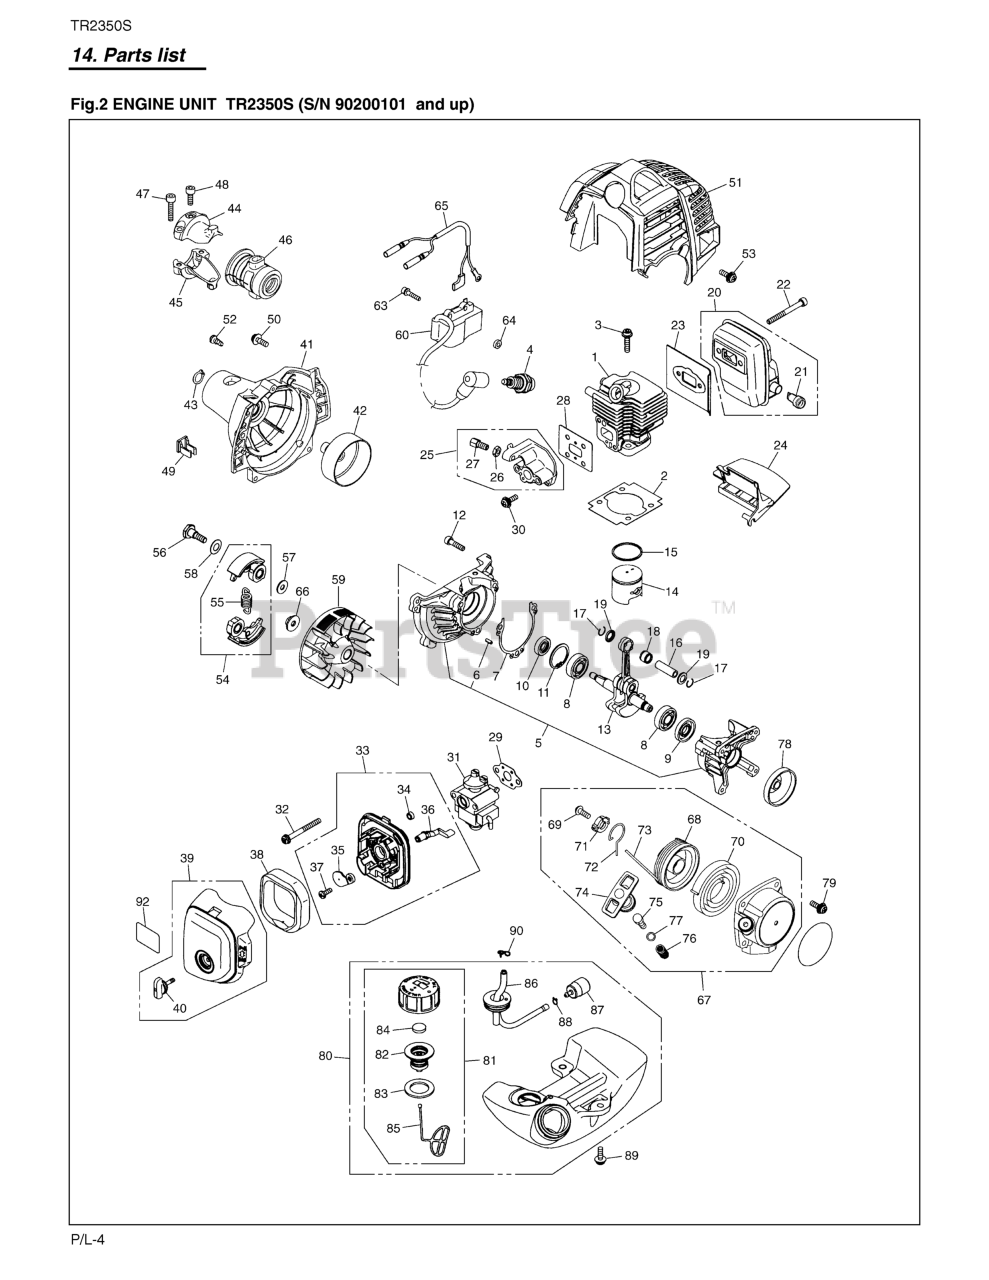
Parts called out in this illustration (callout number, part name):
1	CYLINDER
2	GASKET, BASE
3	BOLT, M5 X 22
4	PLUG (BPMR7A)(RPLS 5933-73110)
5	CRANKCASE-C
6	PIN
7	GASKET, CASE
8	BEARING
9	SEAL
10	SEAL
11	RING, SNAP M26x1.2 R-318013340
12	BOLT, M5 X 20
13	CRANKSHAFT-C
14	PISTON
15	RING, PISTON (RPLS 1850-41210)
16	PIN, PISTON 5x8x26
17	RING
18	BEARING
19	WASHER
20	MUFFLER-A
21	ARRESTER
22	BOLT, M5 x 50
23	GASKET
24	PLATE
25	INSULATOR-C
26	NUT
27	SCREW (RPLS 1918-81170)
28	GASKET (RPLS -13120)
29	GASKET (REPLACES -13130)
30	SCREW
31	CARBURETOR ASSY
32	SCREW (RPLS 0263-30550)
33	BODY ASSY.
34	SLEEVE
35	PLATE, CHOKE
36	LEVER
37	SCREW
38	ELEMENT
39	COVER-A
40	KNOB
41	HOUSING
42	DRUM
43	RING
44	BRACKET (A)
45	BRACKET (B)
46	CUSHION
49	CLAMP
50	SCREW
51	COVER, ENGINE
52	SCREW, M5 X 10
53	SCREW
54	SHOE COMP.
55	SPRING
56	BOLT
57	WASHER
58	WASHER
59	ROTOR
60	COIL
63	BOLT, M4 x 20
64	SPACER
65	CORD COMP.
66	NUT
67	RECOIL-A
68	REEL
69	SCREW
70	SPRING
71	COLLAR
72	ARM
73	ROPE
74	KNOB
75	COLLAR
76	SPRING
77	WASHER
78	PULLEY
79	SCREW
80	TANK ASSY
81	CAP ASSY (RPLS. 5601-85201)
82	HOLDER - A (RPLS 5601-85230)
83	PACKING
84	FILTER
85	STOPPER
86	PIPE COMP
87	FILTER (RPLS 1850-85300)
88	CLIP
89	SCREW
90	CLIP
92	LABEL, CAUTION
NI	LABEL, RECOIL
